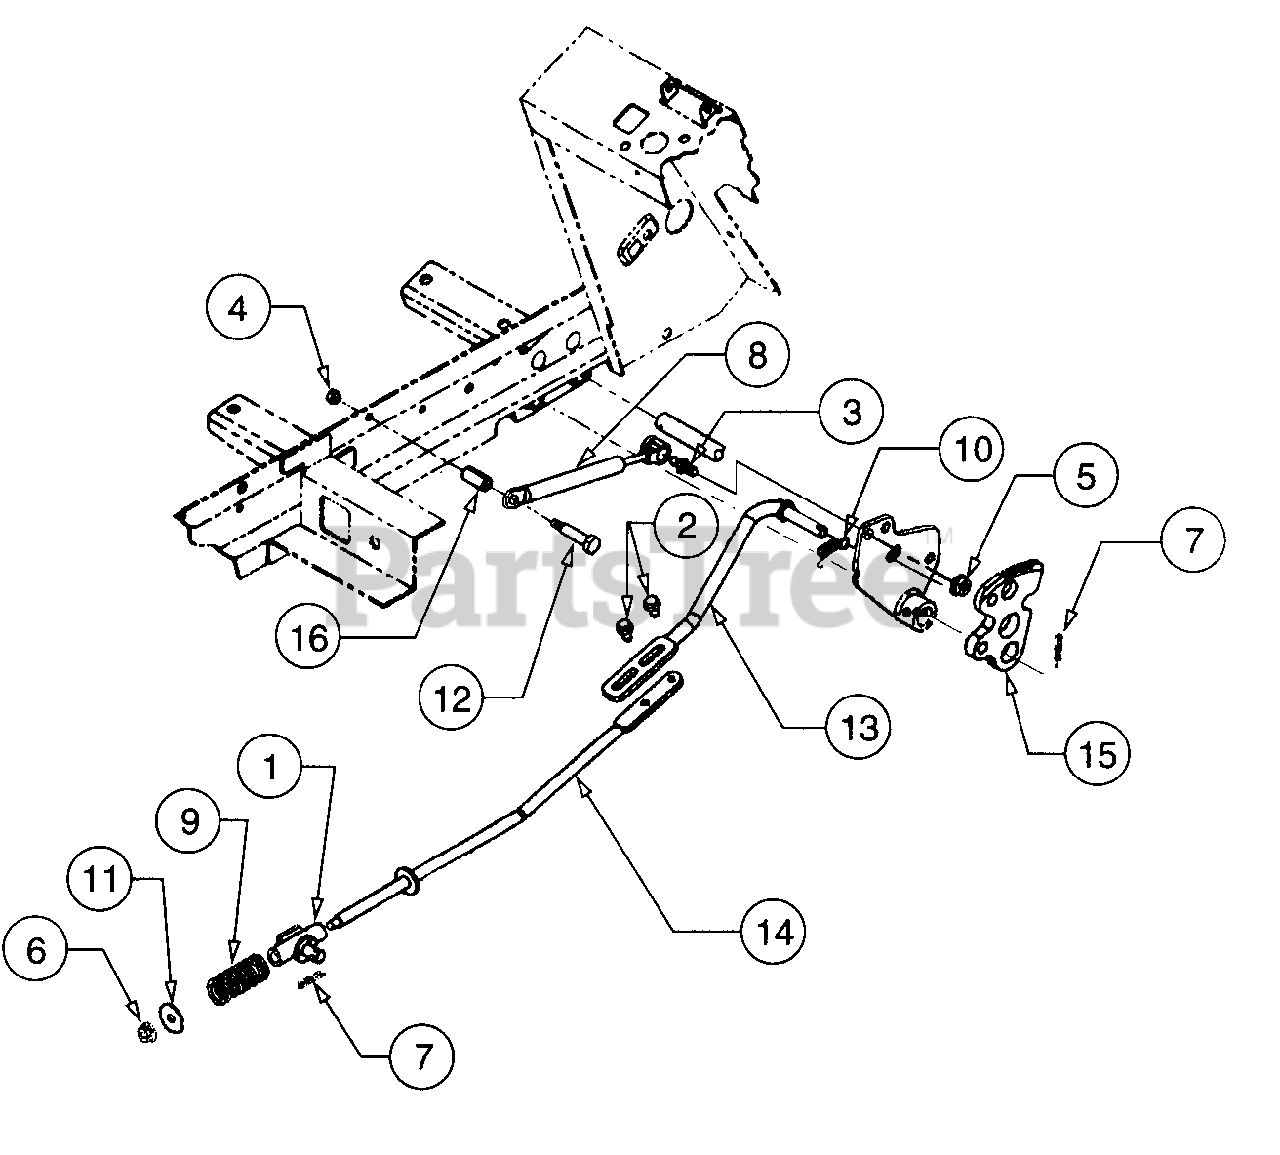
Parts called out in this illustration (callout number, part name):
1	Pivot Assembly
2	Screw, Hex Wash Hd Tapp 1/4-20 x .5
3	Screw, Ball, 5/16-18 x .56
4	Nut, Hex Sems, 1/4-20
5	Nut, Hex Flange Lock, 5/16-18 GR5
6	Nut, Hex Flange Lock, 1/4-20
7	Pin, Internal Cotter
8	Cylinder, Damper
9	Spring, Compression, .63 ID x 2.0 Lg
10	Spring, Extension, 3/8 OD x 1.44
11	Washer, Flat, .265 x 1.0 x .030
12	Bolt, Shoulder, .374 Dia x 1.375
13	Rod, Front Control
14	Rod, Rear Hydro Control
15	Plate, Cruise
16	Spacer, Split Tubing, .375 ID x 1.04
